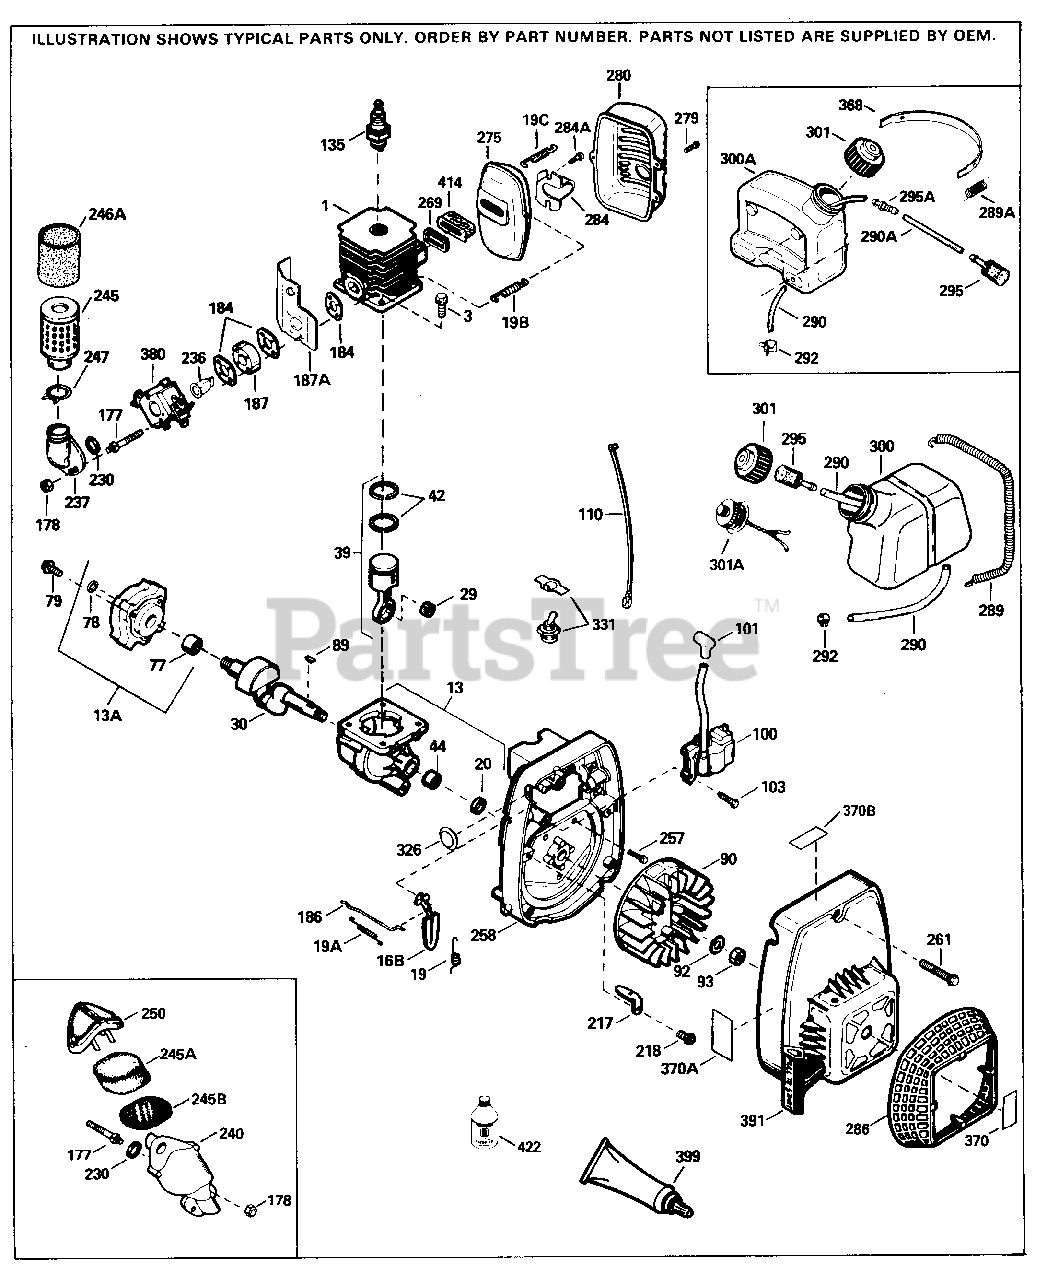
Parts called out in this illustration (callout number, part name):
1	"Cylinder
3	Screw, T-30, 1/4-20 x 43/64
13	Crankcase (Incl. 20 & 44)
13A	Crankcase Cover (Incl. 77 & 78)
16B	Air Vane
19	Governor Spring
19A	Backlash Spring
19B	Muffler Spring
20	Oil Seal
30	Crankshaft
39	Piston & Rod (Incl. 42)
42	Piston Ring Set
44	Cartridge Bearing
77	Cartridge Bearing
78	Oil Seal
79	Screw, 1/4-20 x 3/4
89	Flywheel Key
90	Flywheel
92	Belleville Washer
93	Flywheel Nut, 3/8-24
100	Solid State (Incl. 101)
101	Spark Plug Cover
103	Screw, T-15 10-24 x 1
110	Ground Wire
135	Spark Plug (RCJ-8Y)
177	Air Cleaner Stud
178	Lock Nut, 10-24
184	Carburetor Gasket
186	Governor Link
187	Carburetor Spacer
187A	Carburetor Baffle
217	Speed Adjusting Lever
218	Screw, 8-32 x 1/2
230	Air Cleaner "O" Ring
240	Air Cleaner Body
245A	Air Filter
245B	Air Filter
250	Air Cleaner Cover
257	Screw, 10-24 x 1/2
258	Blower Housing Base
261	Screw, 8-32 x 1-9/16
269	Exhaust Gasket
275	Muffler
286	Starter Screen
289A	Fuel Tank Strap Spring
290	Fuel Line (11" long)
292	Fuel Line Clamp
295	Fuel Fitting & Filter Assy.
300A	Fuel Tank (Incl. 290 & 295)
301	Fuel Cap
368	Fuel Tank Strap (Incl. 289A)
370	Name Decal
370A	Instruction Decal
370B	Caution Decal
380	Carburetor (Incl. 184) (Refer to Divi sion 5, Section A, page A10-4 or Fich e 24, Grid F-9 for breakdown)
391	Rewind Starter & Housing Assy. Refer to Division 5, Section C, page 33 or Fiche 24, Grid G-1 for breakdown
399	Gasket Eliminator
422	2-Cycle Oil with Fuel Stabilizer - 8 oz.
